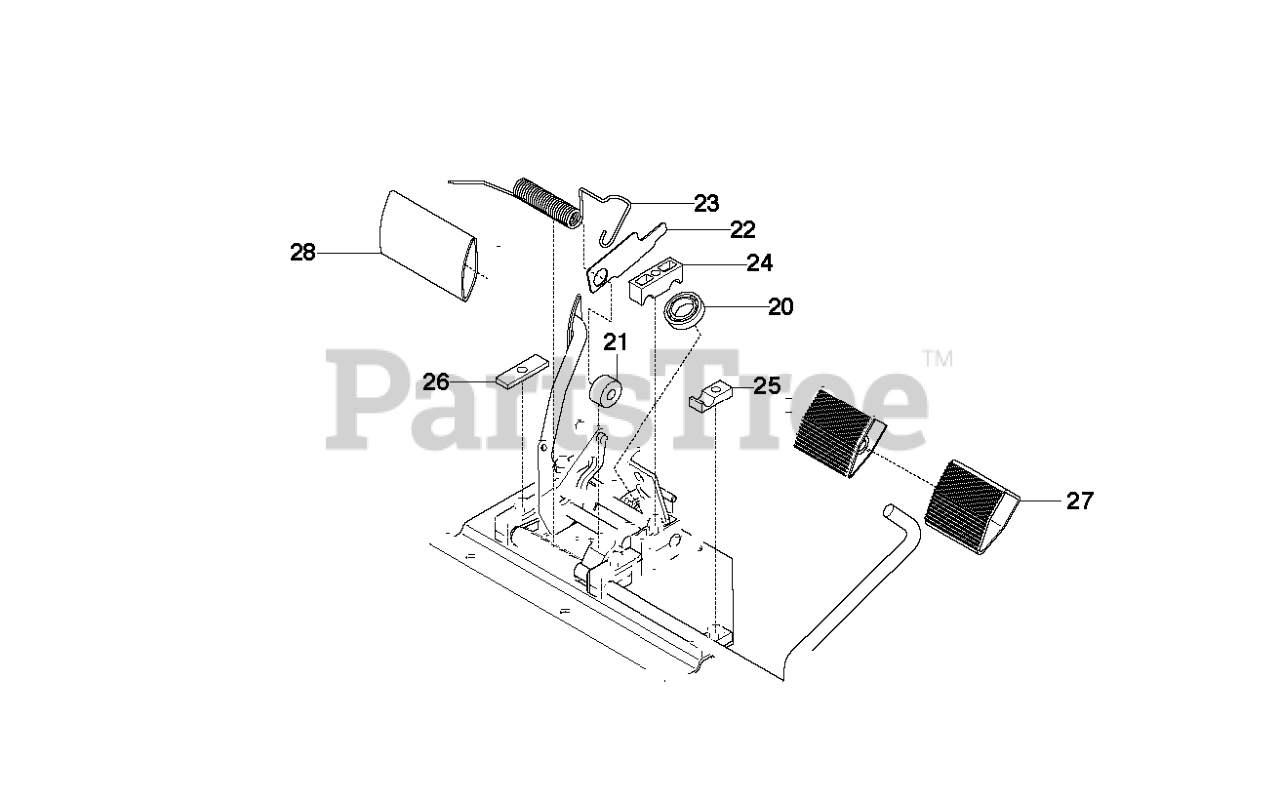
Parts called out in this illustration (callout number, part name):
20	BALL BEARING 6002-2RS1
21	ROLLER
22	PLATE
23	SPRING
24	PEDAL SHAFT CLAMP
25	SUPPORT
26	PLATE
27	PEDAL RUBBER
28	PEDAL RUBBER, SF
